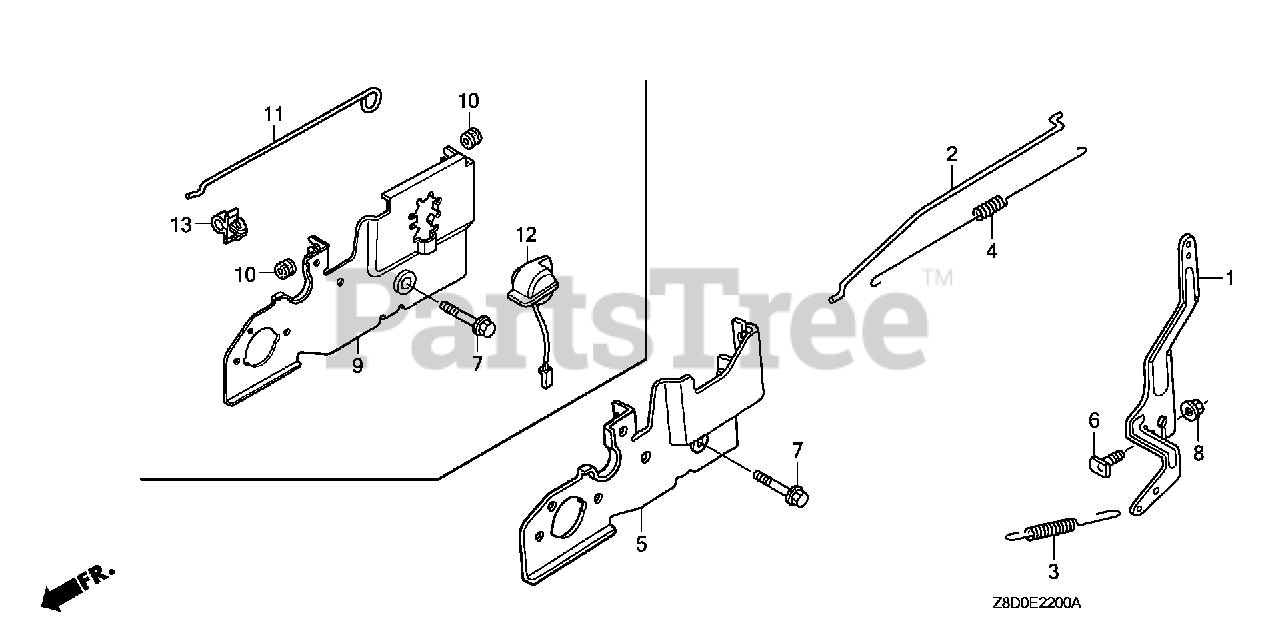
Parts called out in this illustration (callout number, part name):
1	ARM, GOVERNOR
2	ROD, GOVERNOR
3	SPRING, GOVERNOR
4	SPRING, THROTTLE RETURN
6	BOLT, GOVERNOR ARM
7	BOLT, FLANGE (6X45) (CT200)
8	NUT, FLANGE (6MM)
9	BASE, CONTROL
10	GROMMET, CHOKE ROD
11	ROD, CHOKE
12	SWITCH ASSY., ENGINE STOP
13	HOLDER, WIRE (FASTEX)
13	CLIP A, CABLE (3.8MM BLACK) (NIFCO)
